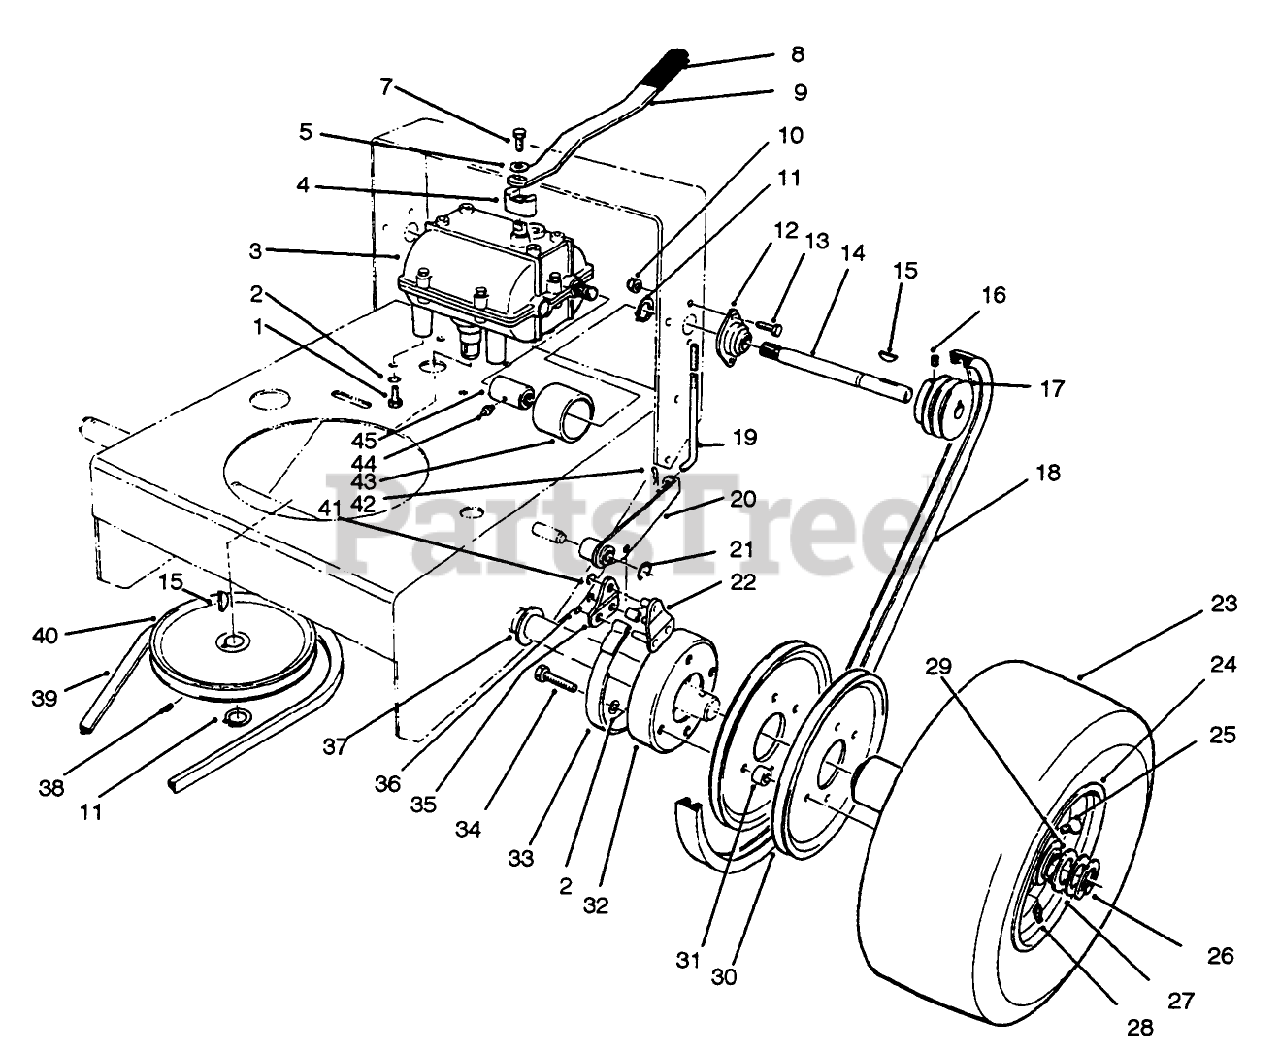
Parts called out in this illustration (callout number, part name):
1	SCREW-HH
2	WASHER-LOCK
3	TRANSMISSION
4	MOUNT-LEVER, SHIFT
5	SPACER
7	SCREW-HH
9	Lever-Shift
10	NUT-LOCK, NI
11	RING-SNAP, EXTERNAL
12	BEARING-EXTERNAL SHAFT
13	SCREW-HH
14	SHAFT-EXTENSION, RH
15	KEY-WOODRUFF
16	SCREW-SET, HS
17	Pulley-Drive
18	V-BELT
19	ROD-BRAKE
20	Brake Arm-LH
21	RING-RETAINING
22	LINK-Brake
24	WHEEL AND HUB ASM
25	STEM-VALVE
26	RING-RETAINING
27	BEARING-BALL
28	FITTING-LUBE, 45 DEG
29	WASHER-THRUST
30	Pulley-Wheel
31	SPACER-PULLEY
32	Drum-Brake
33	BAND-BRAKE
34	SCREW-HH
35	Plate-Link
36	RING-RETAINING
37	WASHER-WHEEL
38	SCREW-SET, HSH
39	BELT V
40	PULLEY-DRIVEN
41	RING-RETAINING, EXTERNAL
42	PIN-COTTER
43	GUARD-COUPLER
44	FITTING-GREASE
45	COUPLER
